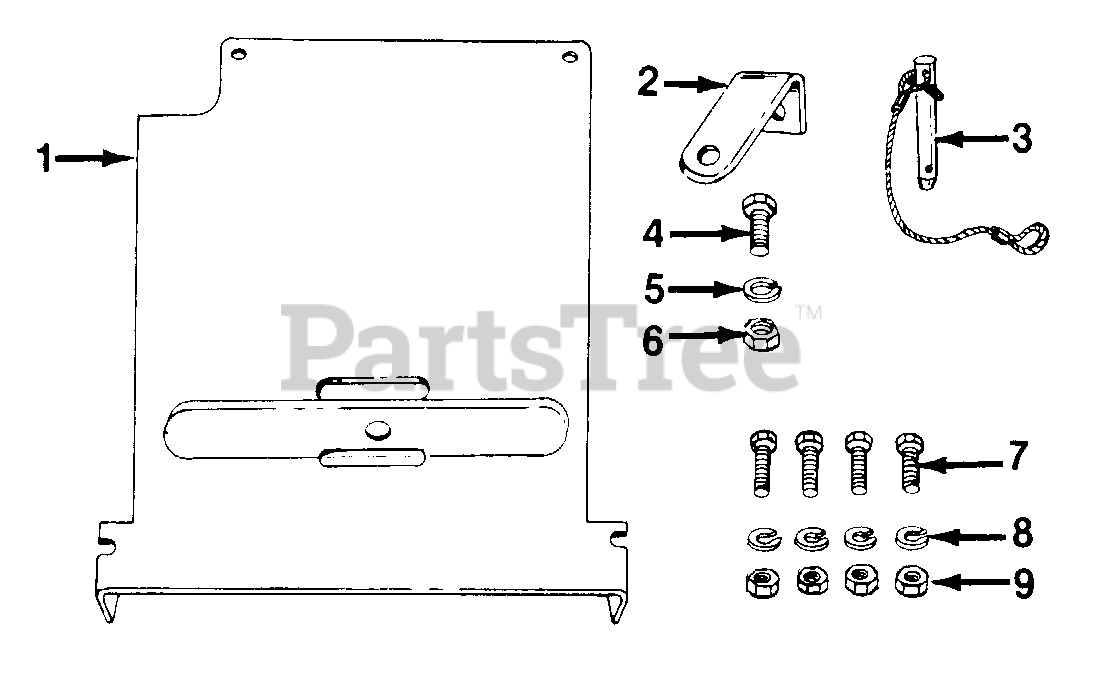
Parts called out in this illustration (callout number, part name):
1	Hitch Plate
2	Hitch Bracket
3	Hitch Pin
4	Hex Scr. 3/8-16 x 1" Lg.
5	L-Wash. 3/8" Scr.
6	Hex Nut 3/8-16 Thd.
7	Hex Scr. 5/16-18 x .75" Lg.
8	L-Wash. 5/16" Scr.
9	Hex Nut 5/16-18 Thd.
